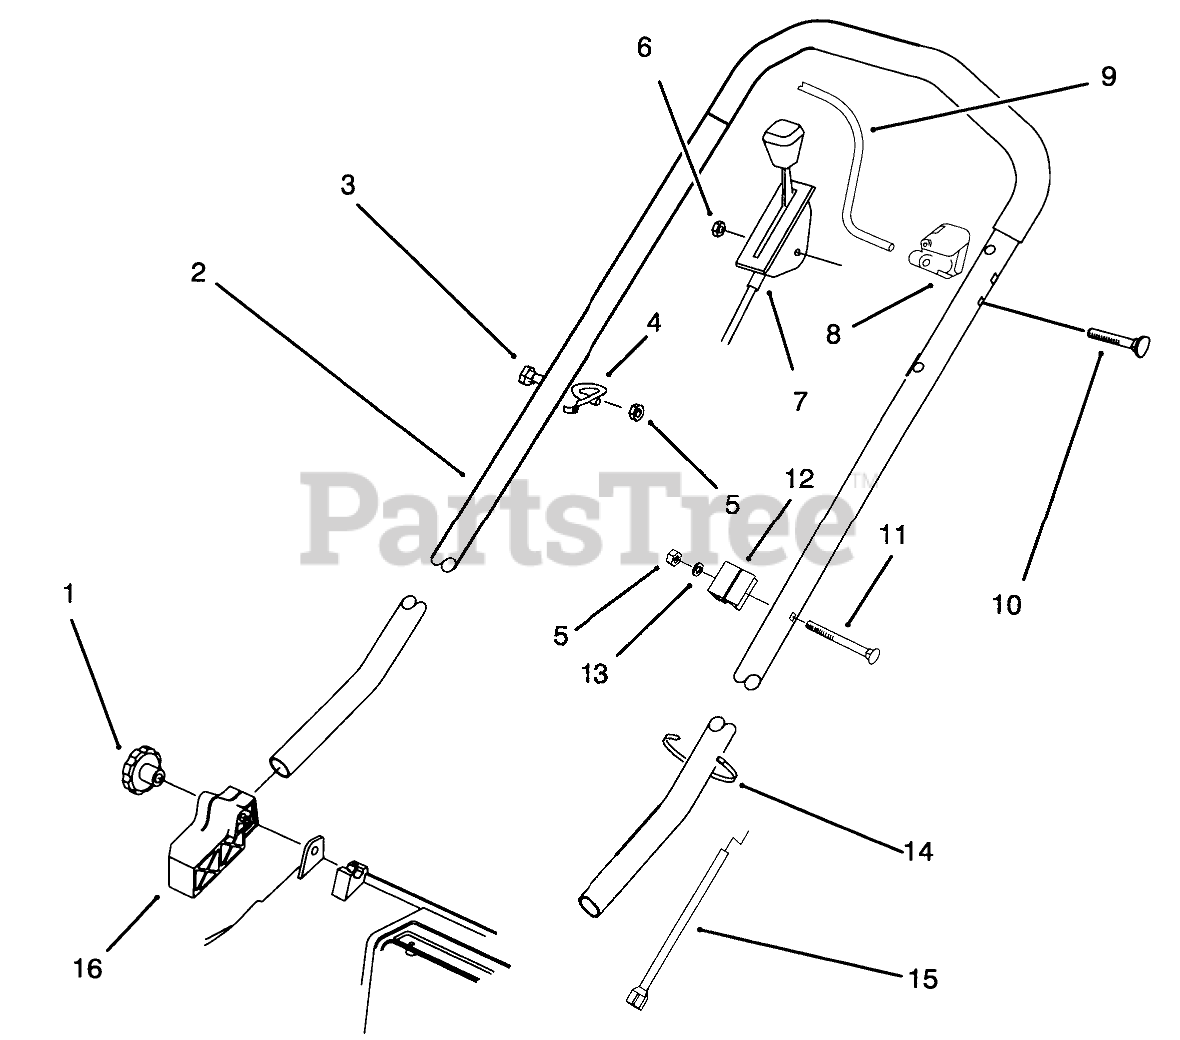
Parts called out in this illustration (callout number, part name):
2	HANDLE (DIPPED)
3	Screw-Handle
4	GUIDE-ROPE
5	NUT-LOCK, NI
6	NUT-LOCK, NI
7	CONTROL - THROTTLE
8	STOP-PIVOT
9	BAIL - CONTROL
10	SCREW-HANDLE
11	SCREW-HANDLE
12	SUPPORT-CABLE
13	WASHER-FLAT
14	TIE-CABLE
15	CABLE - BRAKE
16	MOUNT-HANDLE, RH
